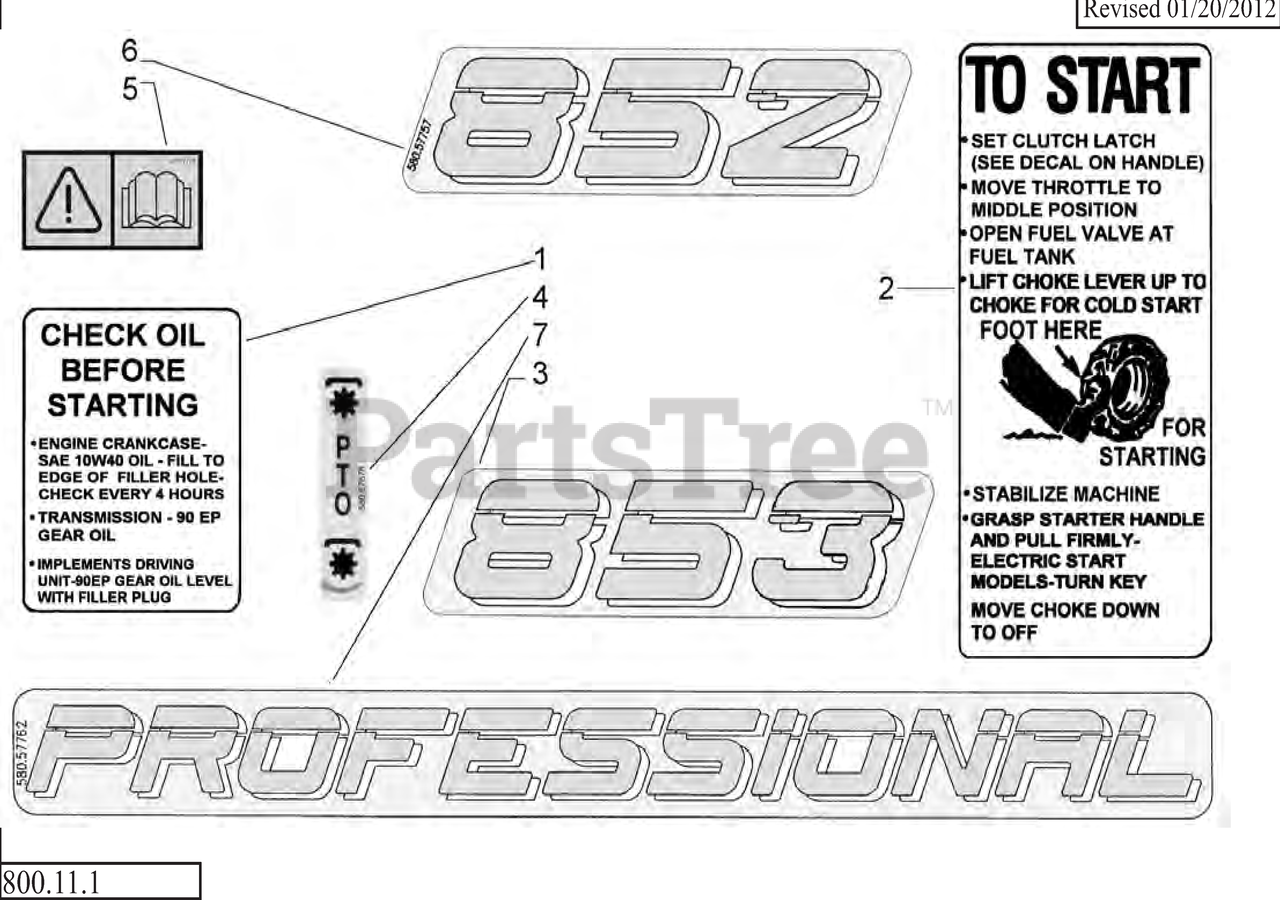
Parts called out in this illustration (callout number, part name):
1	DECAL, CHECK OIL
2	DECAL, TO START
3	DECAL, 853
4	DECAL, PTO
5	DECAL, READ OP MANUAL
6	DECAL, 852
7	DECAL, PROFESSIONAL
